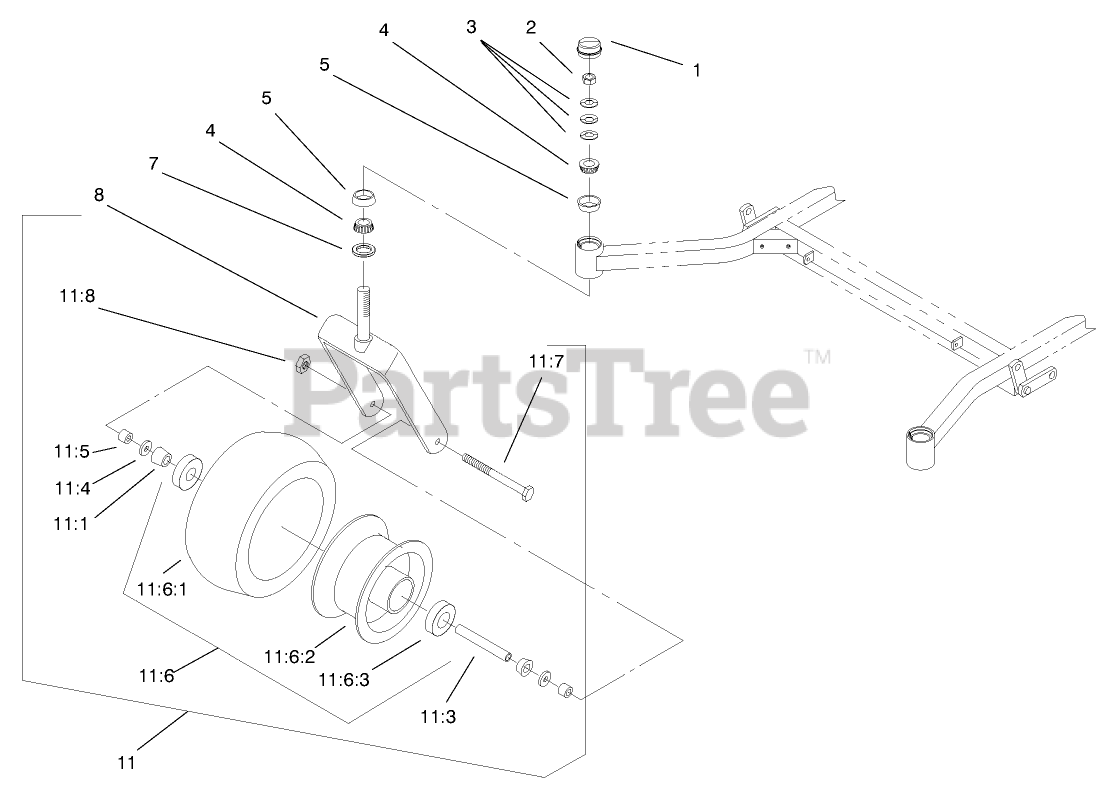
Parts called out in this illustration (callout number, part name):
1	Cap-Grease
2	LOCKNUT
3	Washer-Bellevue
4	BEARING-CONE, TAPERED
5	BEARING-CUP, TAPERED
7	Seal-Grease
8	Caster
11	Caster Wheel ASM
11:1	BEARING-CONE
11:3	Spacer-Front Caster
11:4	Seal-Bearing
11:5	Spacer-Bearing
11:6	Wheel & Tire ASM
11:6:1	Tire
11:6:2	Wheel
11:6:3	BEARING-ROLLER, CUP
11:7	SCREW-HH
11:8	NUT-LOCK, NI
